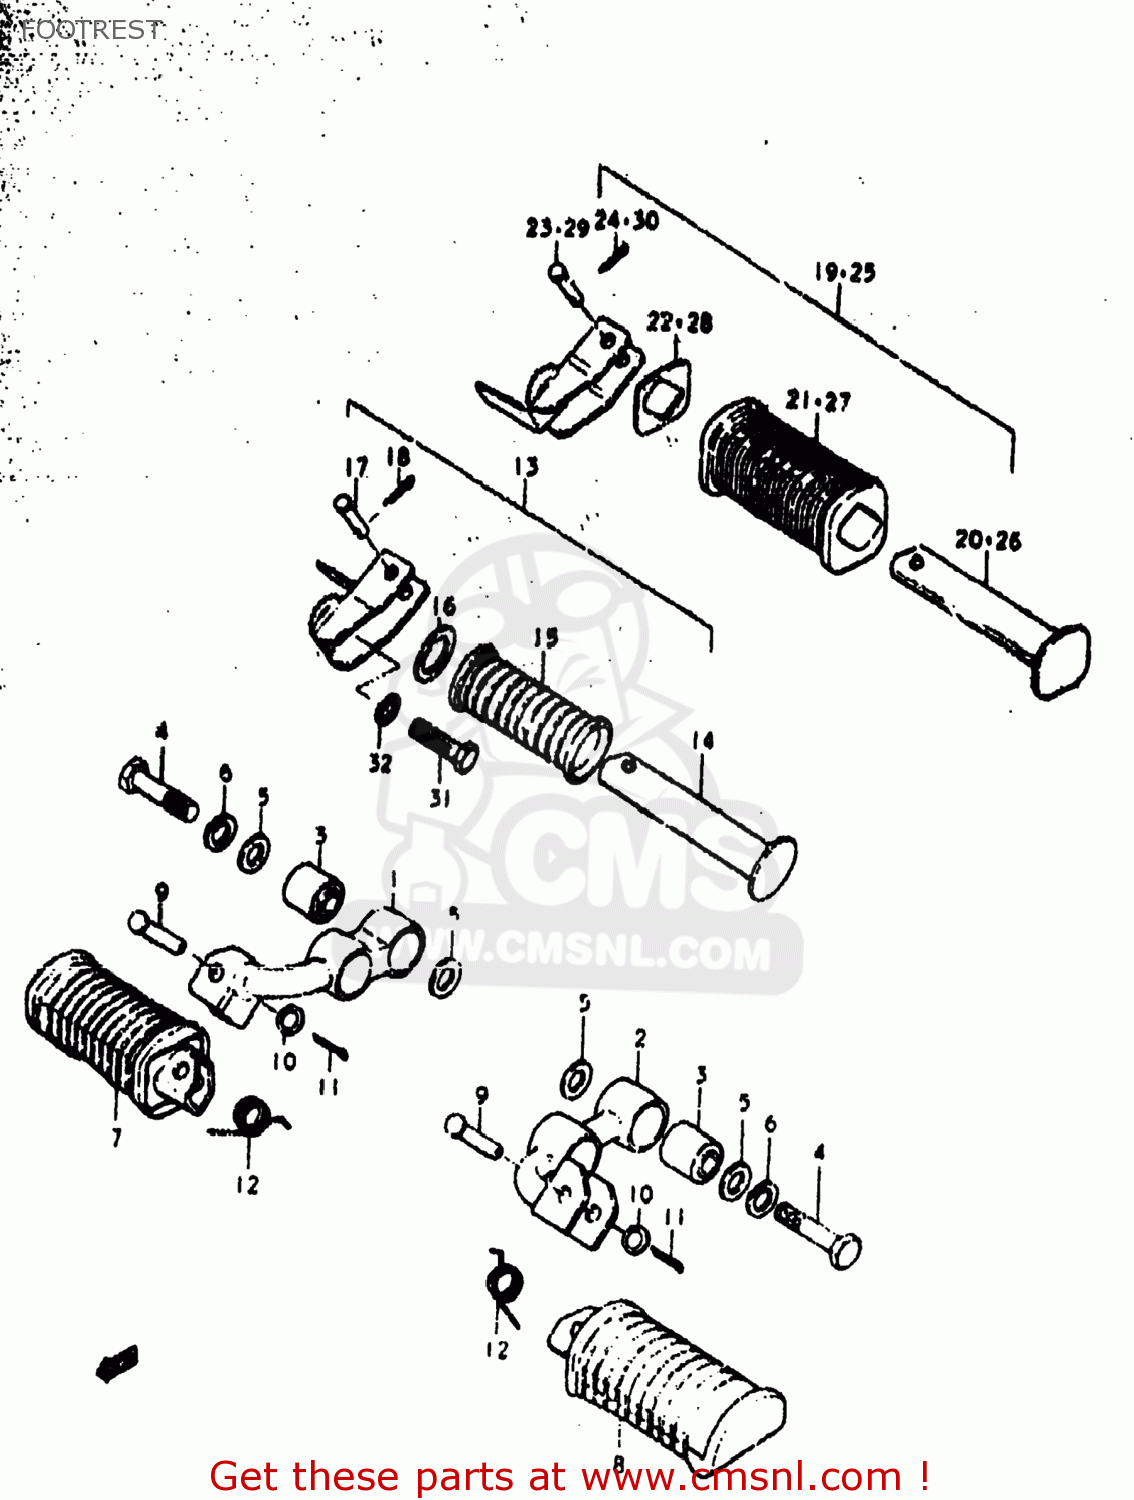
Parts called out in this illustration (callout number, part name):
1	BAR,FRONT FOOTREST
2	BAR,FRONT FOOTREST,LEFT
3	BUSH
4	BOLT
5	WASHER (10.1X21X2.3)
6	LOCK WASHER
7	RUBBER,FRONT FOOTREST
8	FOOTREST
9	PIN
10	WASHER
11	PIN 20X20
12	SPRING
13	FOOTREST ASSEMBLY,REAR
14	BAR,FOOTREST RUBBER
15	RUBBER,PILLION FOOTREST
16	WASHER (19.5X32X2)
17	PIN
18	PIN 20X20
19	FOOTREST ASSEMBLY,REAR
20	BAR,REAR FOOTREST
21	RUBBER,PILLION FOOTREST
22	WASHER,REAR FOOTREST RUBBER
23	PIN
24	PIN
25	FOOTREST ASSEMBLY,PILLION
26	BAR,REAR FOOTREST
27	RUBBER, LH
28	WASHER,REAR FOOTREST RUBBER
29	PIN
30	PIN
31	BOLT 10X30
32	LOCK WASHER
